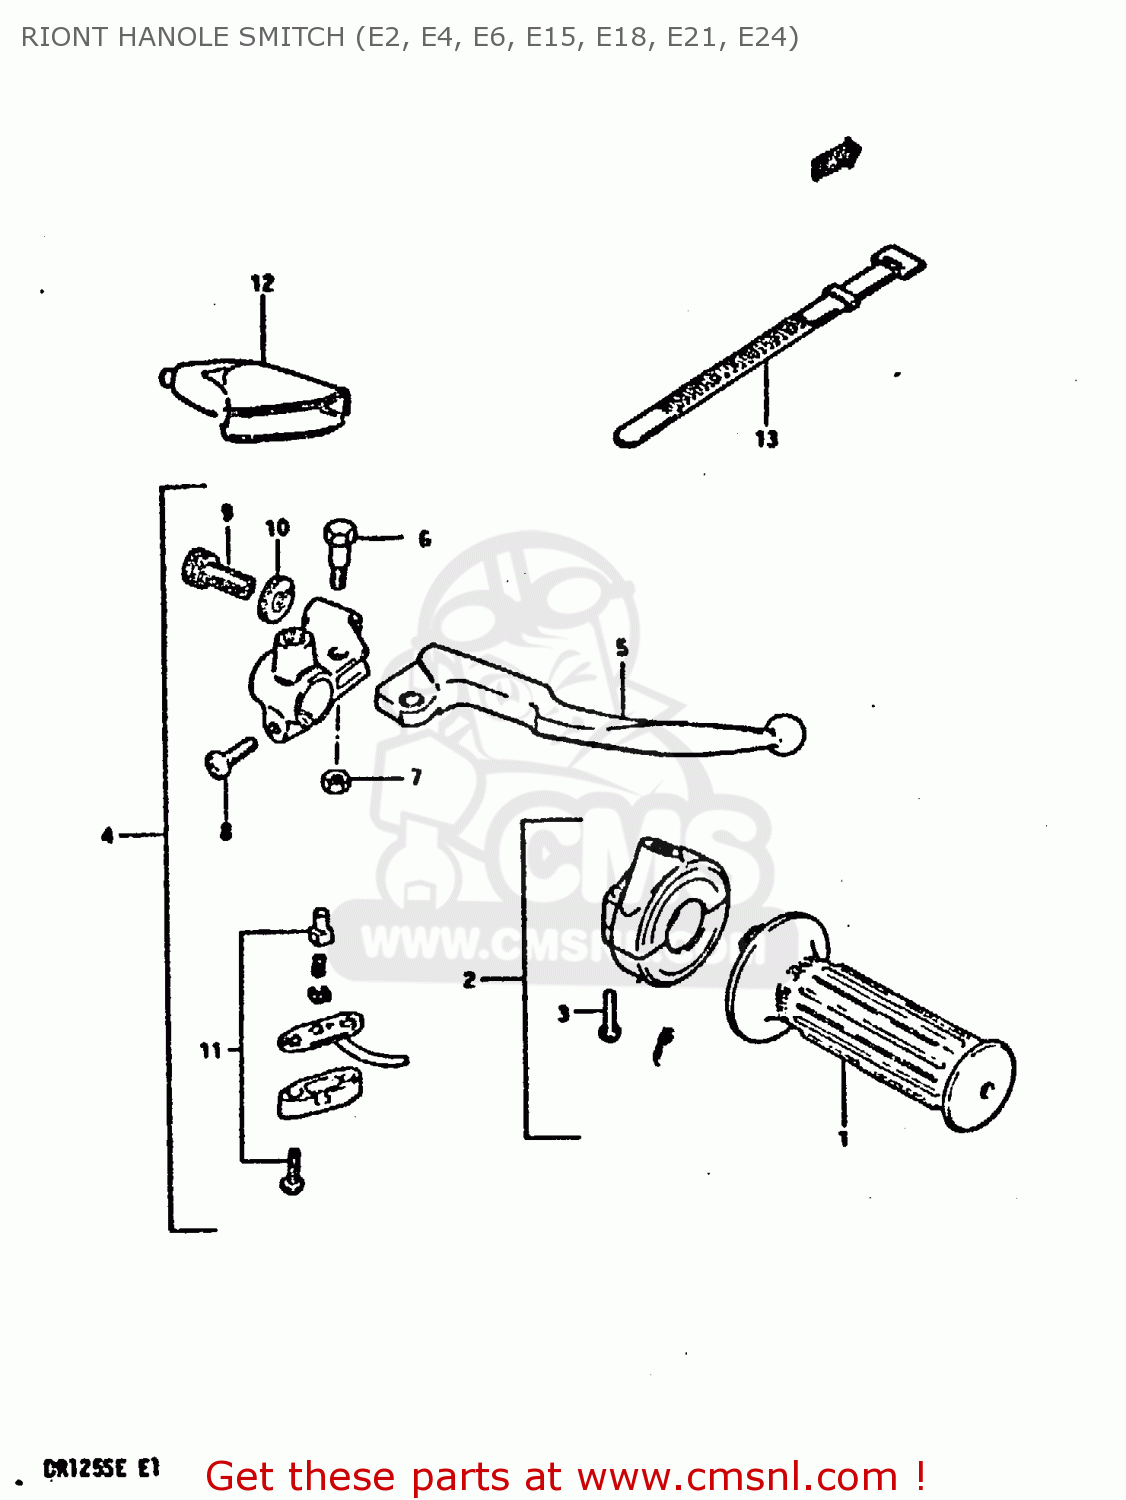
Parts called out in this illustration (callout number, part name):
1	GRIP,THROTTLE
2	CASE ASSY,THROTTLE
3	SCREW
4	LEVER ASSEMBLY,BRAKE
5	LEVER,BRAKE
6	BOLT,LEVER
7	NUT 6MM
8	SCREW
9	ADJUSTER,CABLE
10	NUT,CABLE ADJUSTER
11	SWITCH ASSY,STOP
12	DUST SEAL,BRAKE/CLUTCH
13	CLAMP(L:120)
